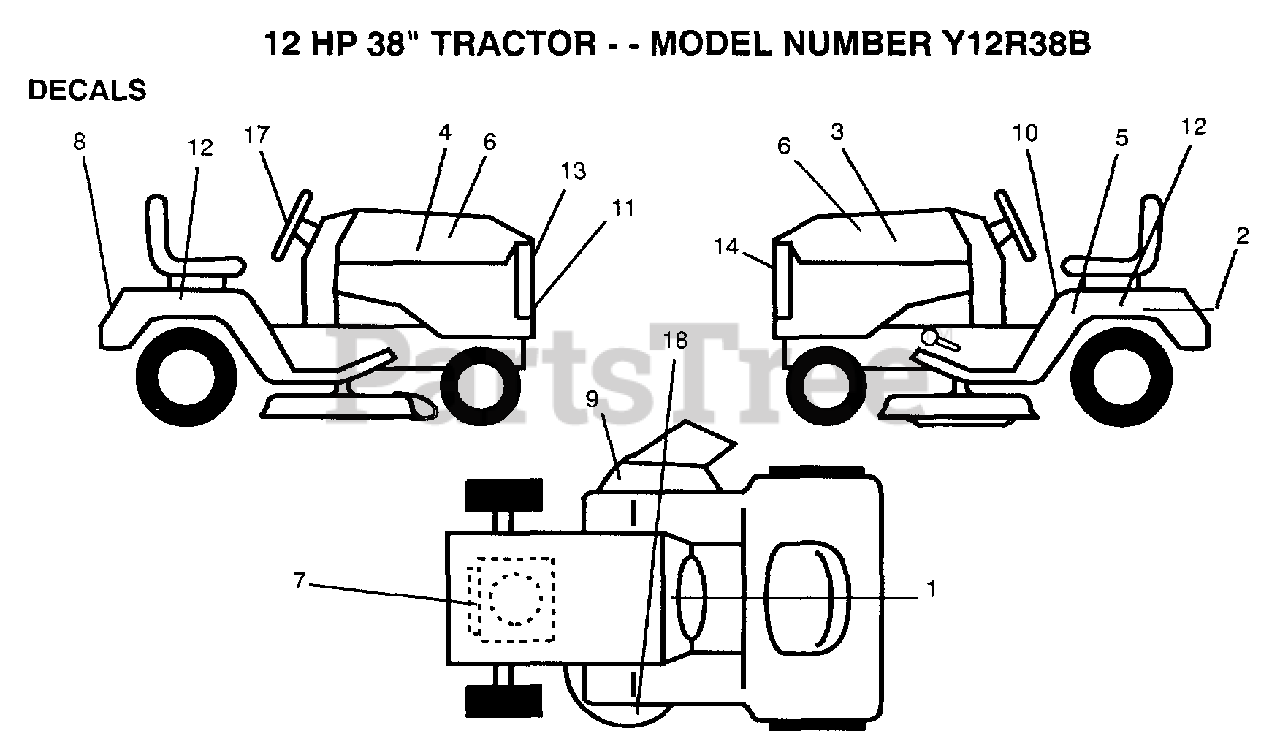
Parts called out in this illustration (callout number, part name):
2	DECAL
5	IND HGT DECK DECA
6	DECAL.PANEL.SD.12
7	DECAL.ENG.271967
9	"DECAL, WARNING"
10	DECAL CAUTION
11	DECAL.GRILL.YARDP
12	DECAL.FEND.QUICKS
13	"DECAL,LIGHT BOX"
14	DECAL.GRILL
17	DECAL.INSERT.STRG
